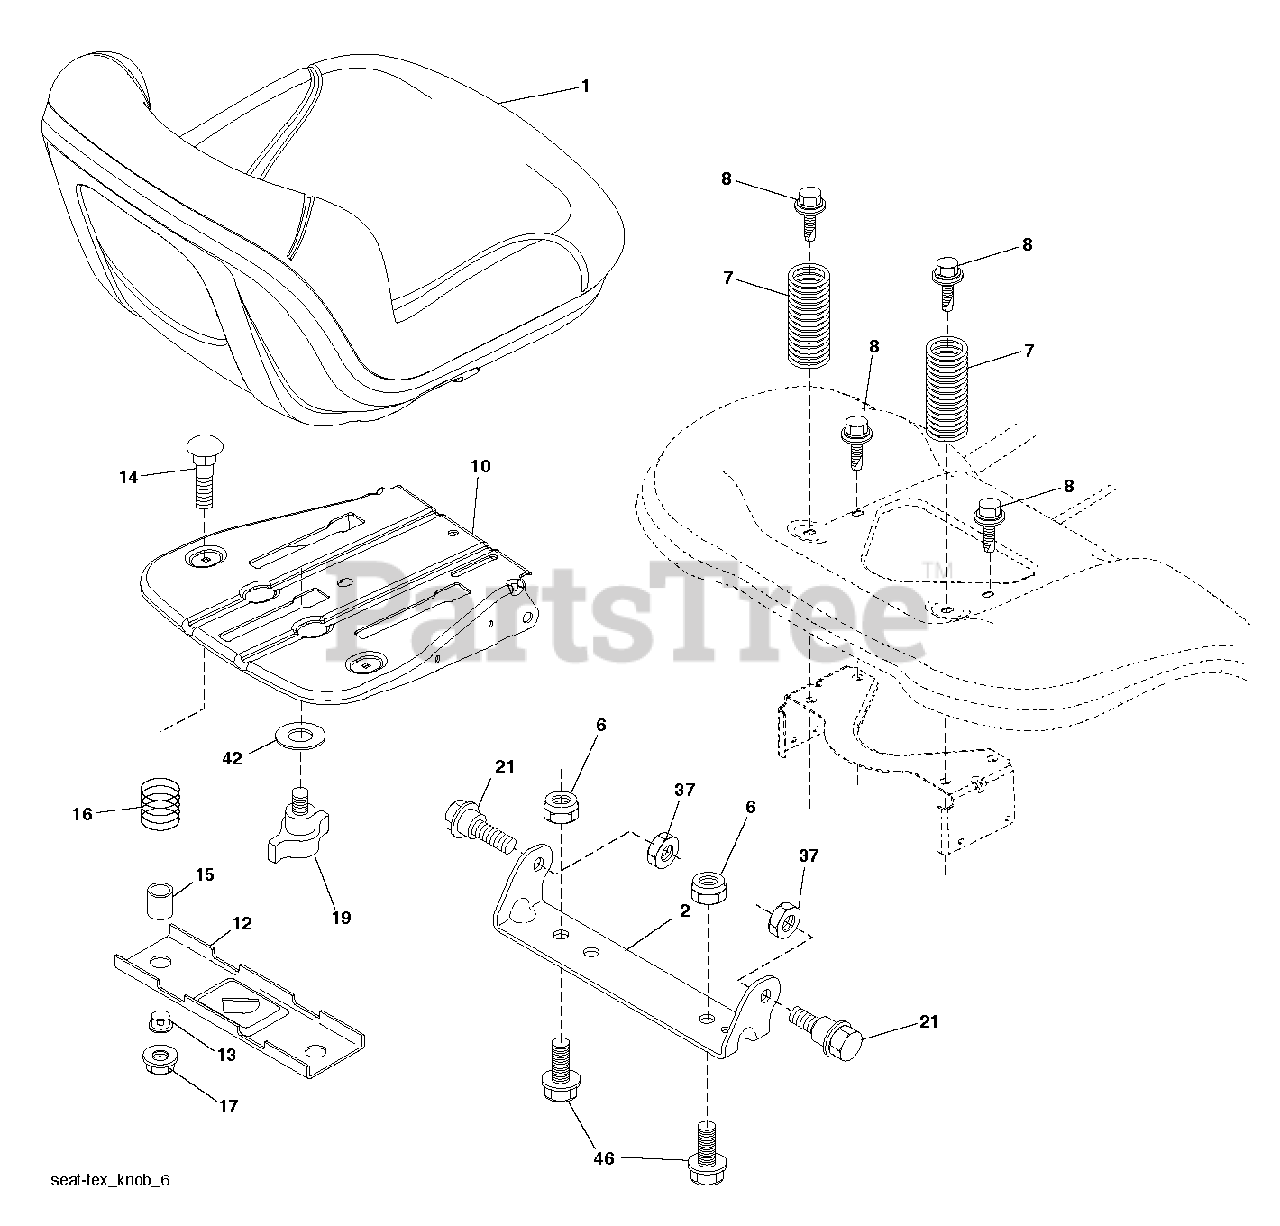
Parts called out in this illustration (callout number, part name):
1	SEAT.TP150.BLK.PPRO.KB/SL
2	BRKT.PIVOT.FENDER
6	NUT
7	Compression Spring, Seat Black
8	BOLT, 5/16-18 X 1 3/4
10	PAN.ASM.SEAT.SHORT.SLD.ADJ.TEX
12	BRKT.MNT.OPC.SW.SEAT.
14	BOLT.ROUND.HEAD.SQUARE.NECK
15	SPACER SPLIT 28X.96
16	SPRING COMPRESSED
17	NUT T
19	KNOB.SEAT.ADJ.
21	Shoulder Bolt, 5/16-18 X 5/8
37	NUT.71038.31-18.HEX.NYLOCK
42	WASHER.CUP.SEAT.
46	BOLT.3/8-16X1;1.25OD.WSHR.SEMS
